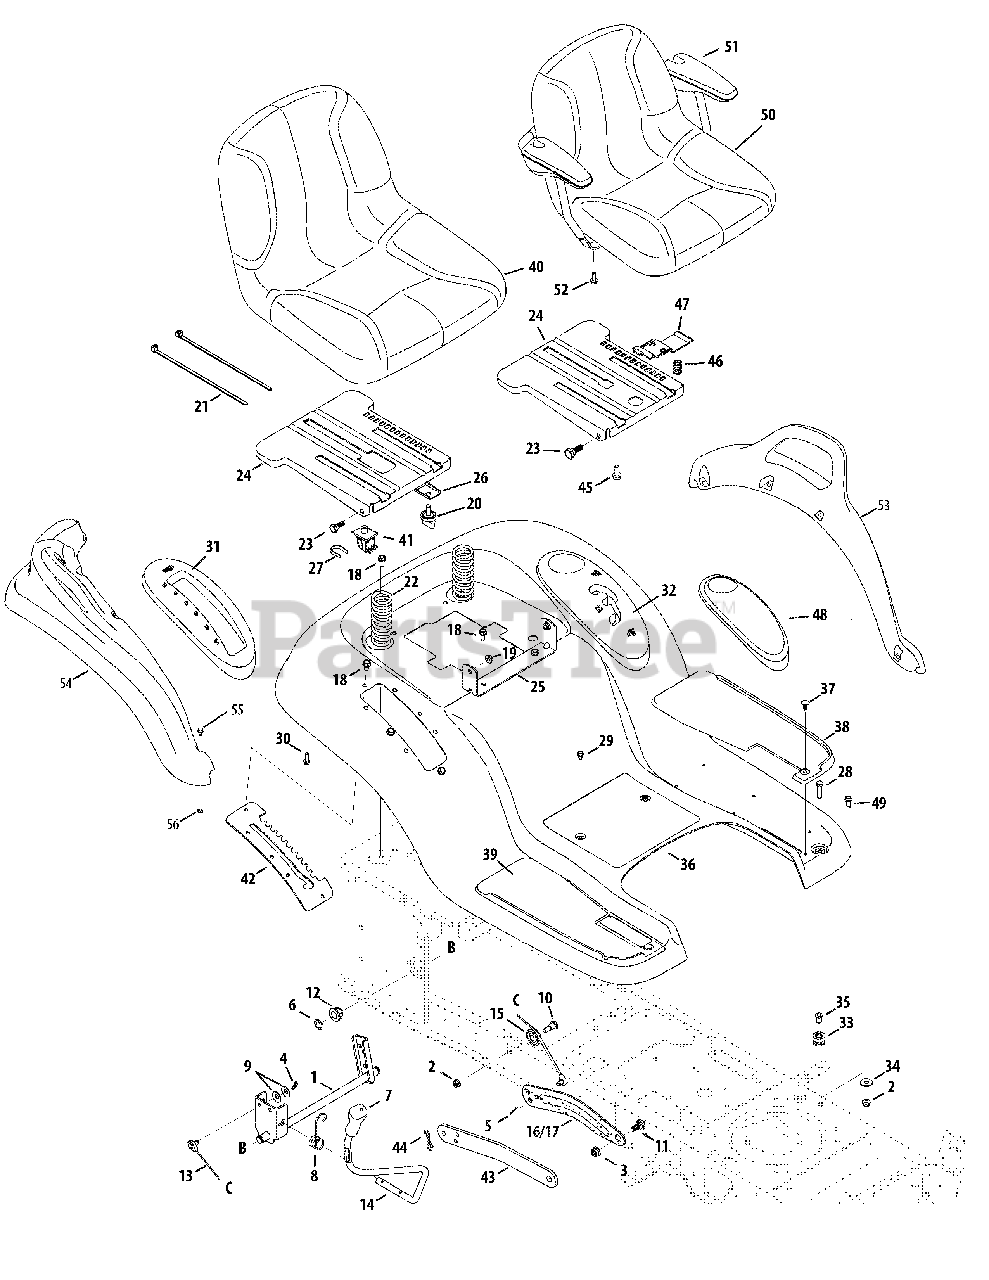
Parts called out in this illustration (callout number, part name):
1	Lift Shaft Ass’y
2	Flange Locknut 5/16-18 Gr. F, Nylon
3	Flange Lock-Nut 3/8-16 Gr. F Nylon
4	Int. Cotter Pin .072 x 1.13" Lg.
5	Bow-Tie Cotter Pin
6	E-ring .625 Shaft
8	Torsion Spring
9	Cupped Washer .375 ID x .870 OD x .063
10	Shoulder Screw. .437 Dia x .47
11	Shoulder Screw .500 x .25 (42")
11	Shoulder Bolt 3/8-16 x .625 (46")
12	Hex Flange Bearing .630 ID
13	Lift Cable, 16.16
15	Roller Pulley
18	Hex Wash Hd. Tapp Screw. 5/16-18 x .75
19	Hex Flange L-Nut 5/16-18
22	Compression Spring 1.71 x 3.735 x .238
23	Shoulder Screw
24	Seat Mounting Bracket
25	Seat Pivot Bracket
26	Seat Bracket, Knob adjustment
27	Switch Retaining Clip
28	Hex Bolt 5/16-18 x 1.25
29	Hex Wash S-Tapp Screw 1/4-20 x .50
30	Hex Tapp Screw 1/4 x .75" Lg.
31	Lift Lever Cover
32	Shift Lever Cover
33	Grommet .4375 ID x .75
34	Flat Washer .344 ID x 1.0
35	Flange Spacer .3125 x .4375 x .625
36	Fender (used with fender covers)
37	Foot Pad Clips
40	Seat, High Back, Black
42	Lift Bracket 6 positions (w/Electric pto)
43	Lift Link (46"/50")
44	Bow-Tie Cotter Pin (46")
45	Hex. Hd. Flg. Screw. 3/8-16 x .875
46	Compression Spring .68 x 1.065 x .055
47	Seat adjustment Lever
48	Cover (Hydrostatic Models only)
49	Hex Wash. Hd. Screw. 5/16-18 x .75 Gr. F Nyl.
50	Seat, High Back, Black (w/arm rest option)
51	Arm Rest (incl. R&L)
52	Pan TT Screw 5/16-18 x .75
53	Fender Cover LH
54	Fender Cover RH
55	Carriage Bolt 14-20 x 1.0
56	Sems Hex Nut 1/4-20
